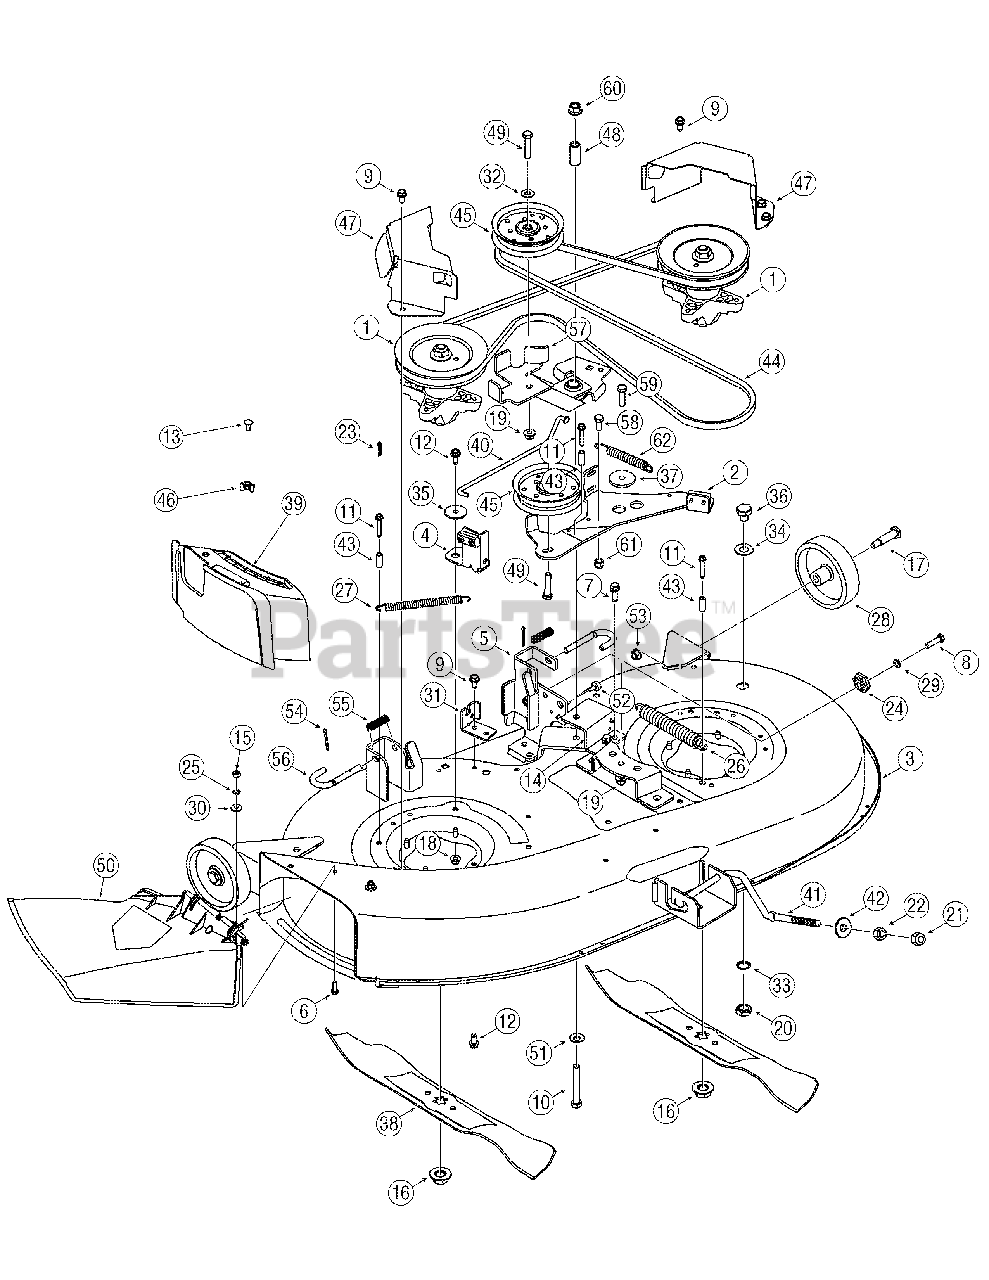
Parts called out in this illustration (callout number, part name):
1	Spindle Assembly, Pul, 6.23"
6	Screw, 1/4-20, .75, Gr5
7	Screw, 3/8-16, 1.00
8	Screw, 5/16-18, 1.250
9	Screw, 5/16-12, 0.750
10	Screw, 7/16-20, 3.00, Gr5
11	Screw, 1/4-20, 1.500
12	Screw, 5/16-18, .75
13	Carriage Screw, , 1/4-20 x .62
15	Nut, Hex, 1/4-20, Gr5
16	Nut, Flange, 5/8-18
17	Screw, Shldr, .498 x 1.53,
18	Nut, Flange Lock, 5/16-18,
19	Nut, Flange Lock, 3/8-16,
20	Nut, Hex, M16-1.5
21	Nut, Hex Lock, 1/2-13, Gr8
22	Nut, Hex, 1/2-13, Gr5
23	Pin, Cot, .072 Dia. x 1.13
24	Gear, Deck Adjustment
25	Nut, Push, .25 ID x .50
26	Spring, Exten. , .94 Dia.
27	Spring, Exten. , .50 Dia.
28	Wheel, Deck 5.0 x 1.38
29	Washer, Lock, 5/16
30	Washer, Bell, .265 x.75 x
32	Washer, Flat, .406 x .875
33	Washer, Lock
34	Washer, Flat, .64 x 1.24
35	Spacer, Shoulder, .5000 x .1475
36	Plug, Screw, M16 x 1.5
37	Spacer, Shoulder, .8840 x .190
38	Blade, 21.23", Star 3-in-1
39	Mulch Plug
40	Control Rod, Brake
41	Deck Rod, Front Adjustable
42	Pivot Cup, Deck Lift
43	Spacer, .260 x .372 x 1.030
44	Belt, V-Type
45	Idler Pulley, 4.25" Dia.
46	Wing Nut, 1/4-20
48	Spacr, .455 ID x .680 OD
49	Screw, 3/8-16 x 1.75
50	Chute Assembly, Discharge
51	Bell Washer, .45 x 1.00 x .062
52	Bumper
53	Flange Lock Nut, 3/8-16
54	Cotter Pin
55	Comp. Spring, .531OD x 1.75 lg
56	Deck Release Rod
58	Screw, 3/8-16 x .75
59	Screw, 3/8-16 x 1.25
60	Flange Lock Nut, 7/16-20
61	Hex Lock Nut, 3/8-24
62	Extension Spring, .53 OD x 4.75
